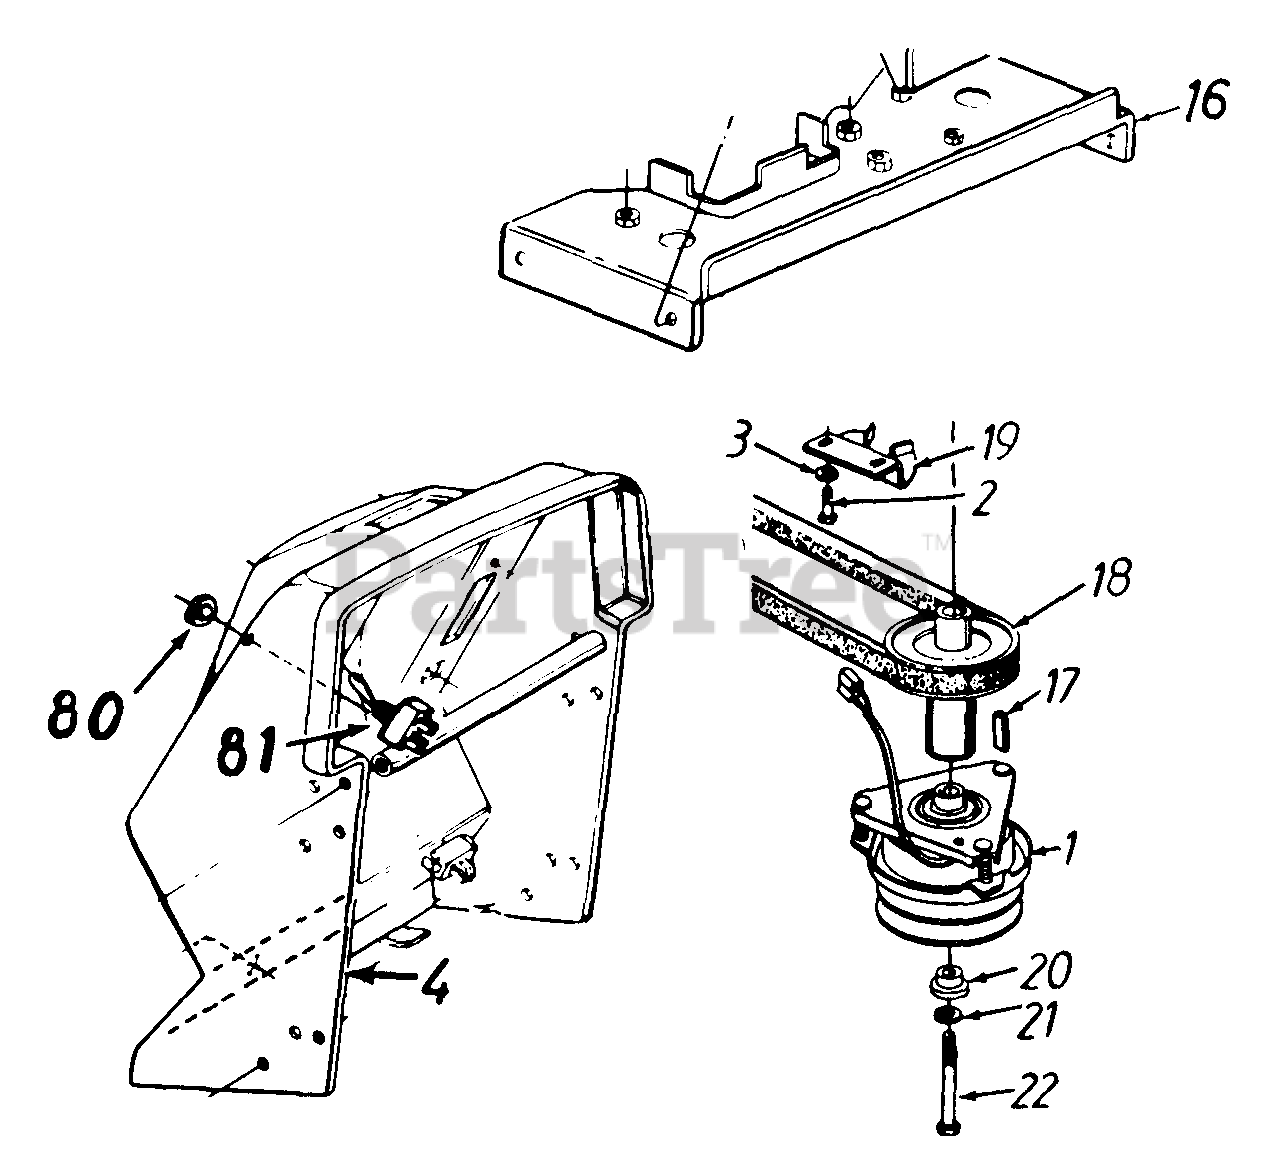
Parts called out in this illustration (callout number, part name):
1	Electric Clutch
2	Hex Bolt 5/16-18 x .75" Lg. (Gr. 5)
3	Bell-Wash. .345" 1.0. x .88"
16	Belt Guard Brkt. Ass'y.
17	Sq. Key 1/4" x 1.5" Lg.
18	Engine Pulley
21	L-Wash. 7/16" I.D.
22	Hex Bolt 7/16-20 x 5" Lg. (Gr. 5)
80	Hex Nut 1/2-27 Thd.
81	PTO Switch
